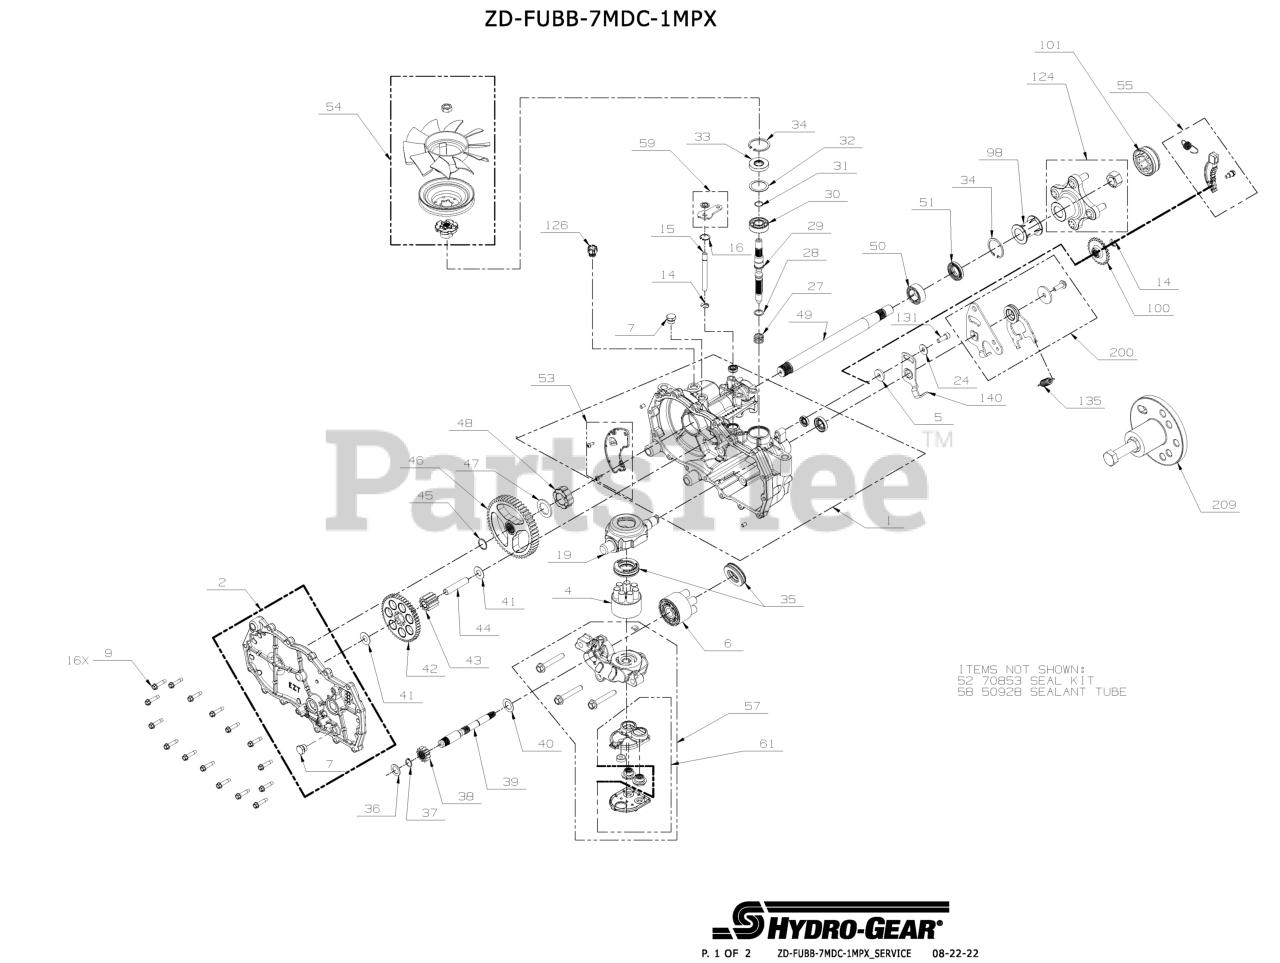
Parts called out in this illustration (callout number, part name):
1	KIT, HOUSING MAIN, LH
2	KIT, SIDE HOUSING, LH W/DRAIN
4	ASSY, BLOCK 7 PISTON
6	KIT, 10 CC BLOCK
7	PLUG EXT HEX VENT 9/16 18
9	SCREW,HEX WASHER 1/4-20X1.125
14	RING. RETAINING
15	ROD, BYPASS
16	RING, RET .750
19	TRUNNION, SWASHPLATE
27	SPRING. BLOCK
28	WASHER. THRUST .59 X .79 X .04
29	SHAFT, INPUT
30	BRG, BALL 17X40X12
31	RING, RET WIRE .561 ID
32	WASHER 1.23X1.56X.04
33	SEAL, LIP 17X40X7
34	RING, RET 1.56 INT
35	BEARING. THRUST 30 X 52 X 13
37	RING, RET 62 EXT
39	SHAFT, MOTOR
40	WASHER .71 X 1.16 X .04
41	WASHER .5X1.0X.032
43	GEAR, 10T JACKSHAFT
44	PIN, JACKSHAFT
47	WASHER, 1.018 X 1.571 X .105 FLAT
48	BUSHING, SLEEVE (INBOARD)
49	SHAFT, AXLE
52	KIT, SEALS AND RETAINING
53	KIT, EXPANSION PLATE LH
54	KIT, FAN/PULLEY
55	KIT, BRAKE ARM
57	KIT, CENTER SECTION, W/FILTER - LH
58	SEALANT TUBE 10.1OZ.
59	KIT, BYPASS ARM
61	KIT, FILTER
100	DISC, COG BRAKE
101	CAP, AXLE
124	KIT, HUB 4 BOLT
126	ASSEMBLY, FITTING 9/16-18 BREATHER
131	KIT, RTN SCREWS
135	SPRING, EXTENSION
140	ARM, NEUTRAL LEFT
200	RING, RTNG .
209	HUB PULLER 5 BLT
